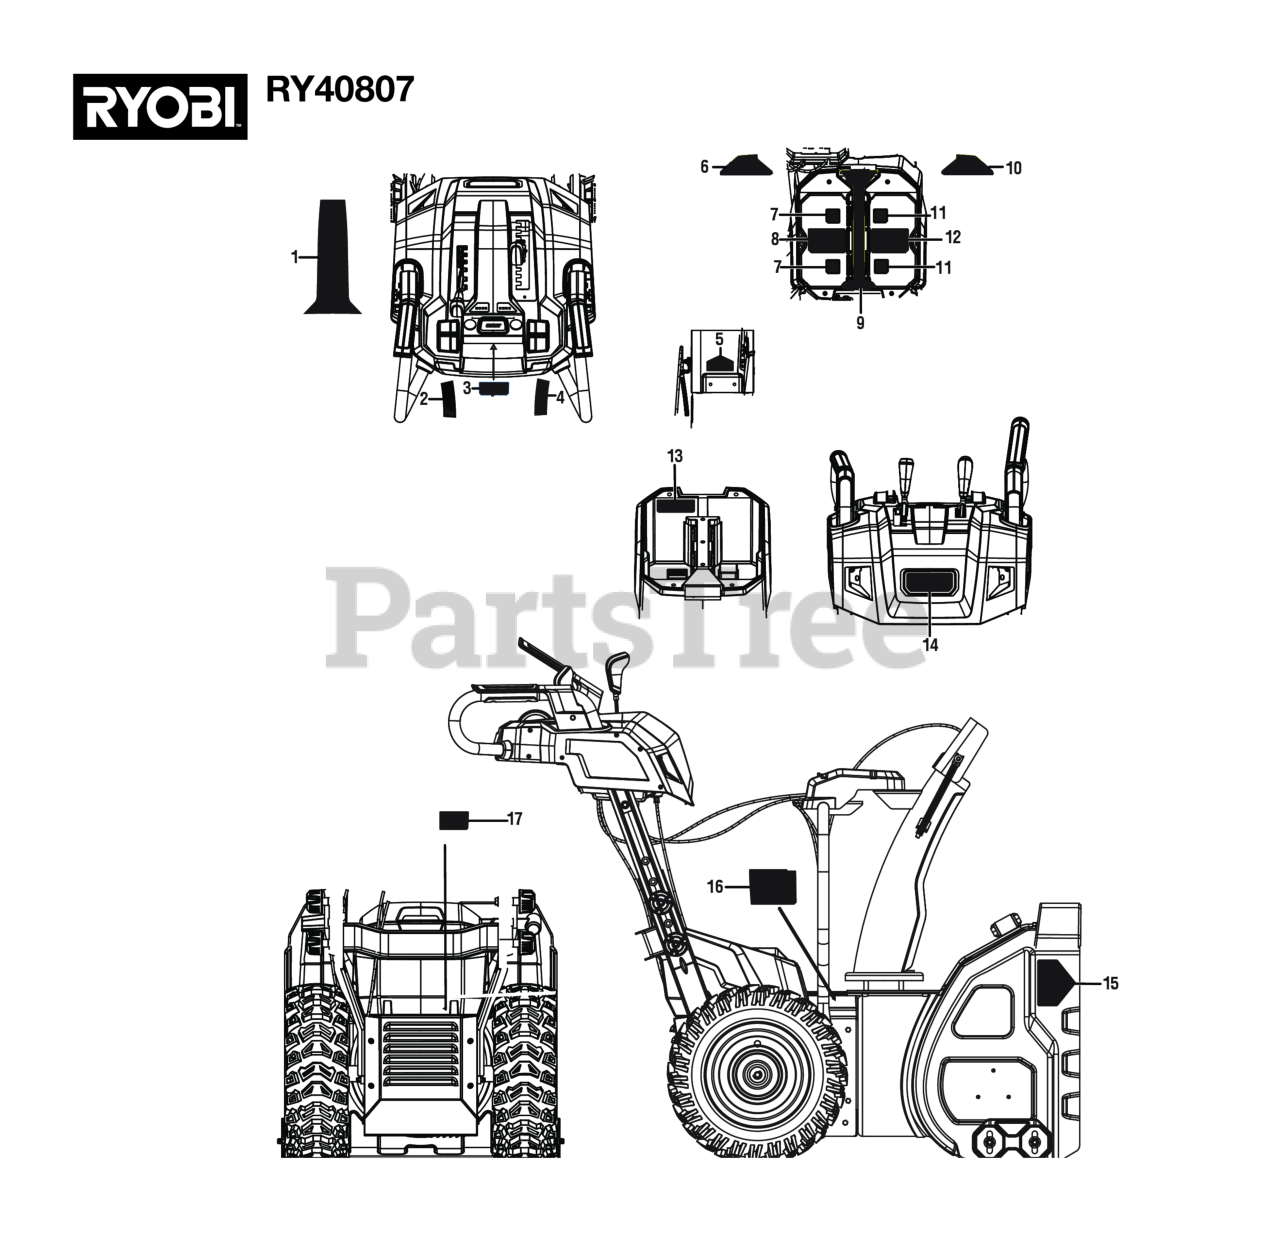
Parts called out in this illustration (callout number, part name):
1	Handle Controls / Fuel Gauge
2	Drive Speed Label
3	Starting Instructions
4	Auger Speed Label
5	Chute Warning Icons Label
6	Battery Icon (Left)
8	A Min Battery Label
9	Qr Code / Center Label
10	Battery Icon (Right)
12	B Min Battery Label
13	Battery Notice Label
14	Ryobi 40v Hp Label
15	Danger Label (No Hands/Feet)
16	Icon/Danger / Caution Label
17	Data Label
